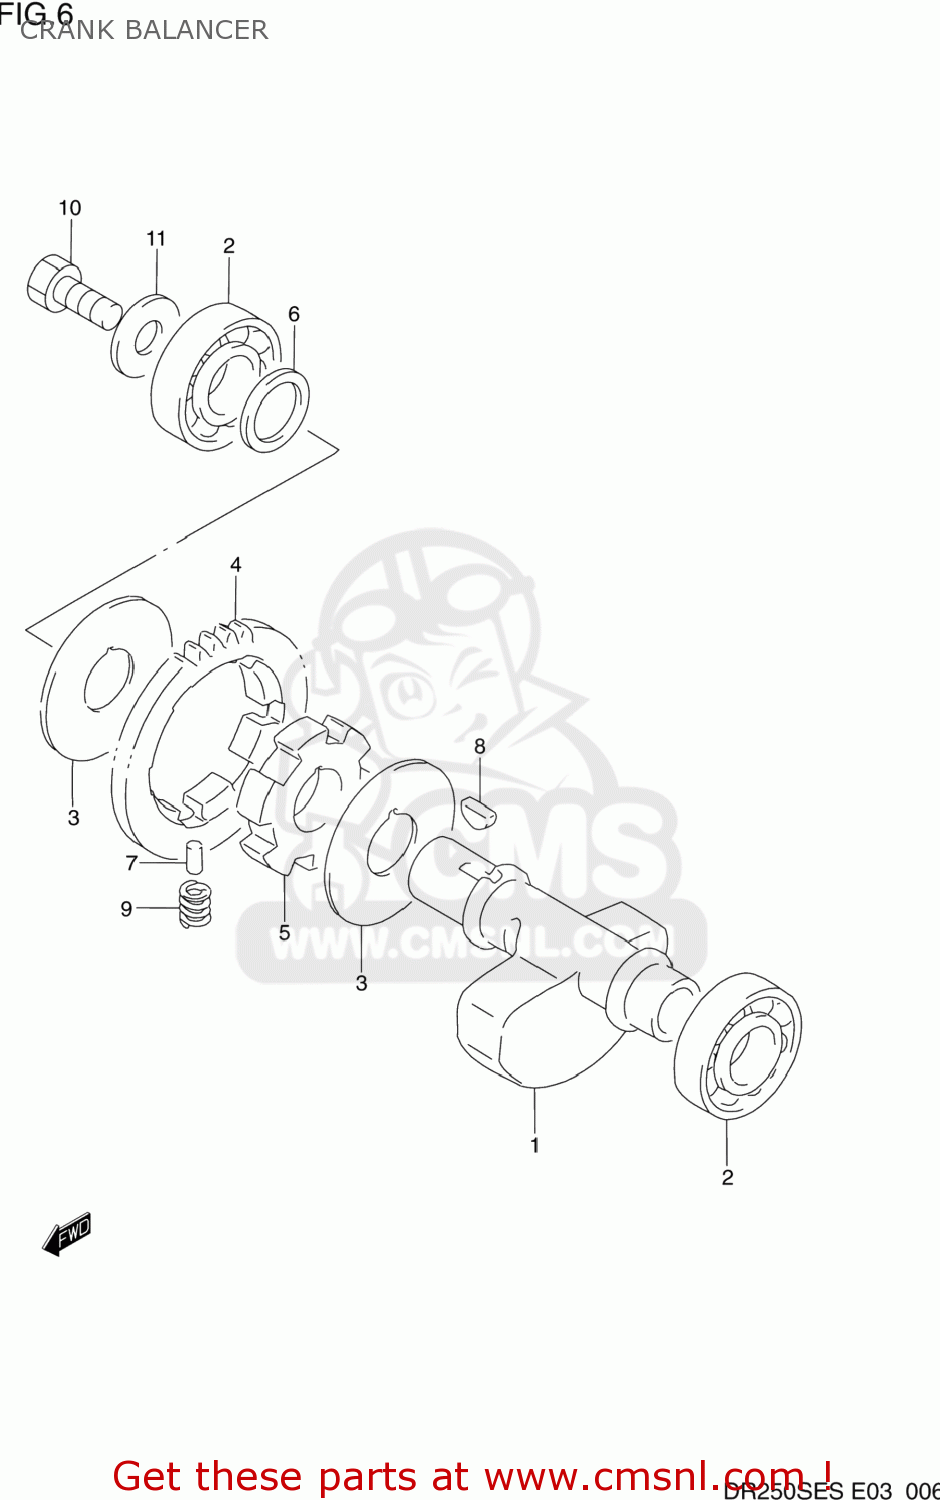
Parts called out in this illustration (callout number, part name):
1	BALANCER CRANK
2	BEARING(20X47X14)
3	WASHER
4	GEAR,CRANK BALANCER
5	RACE,CRANK BALANCER DRIVEN GEAR
6	THRUST WASHER
7	PIN
8	KEY
9	SPRING
10	BOLT
11	WASHER
